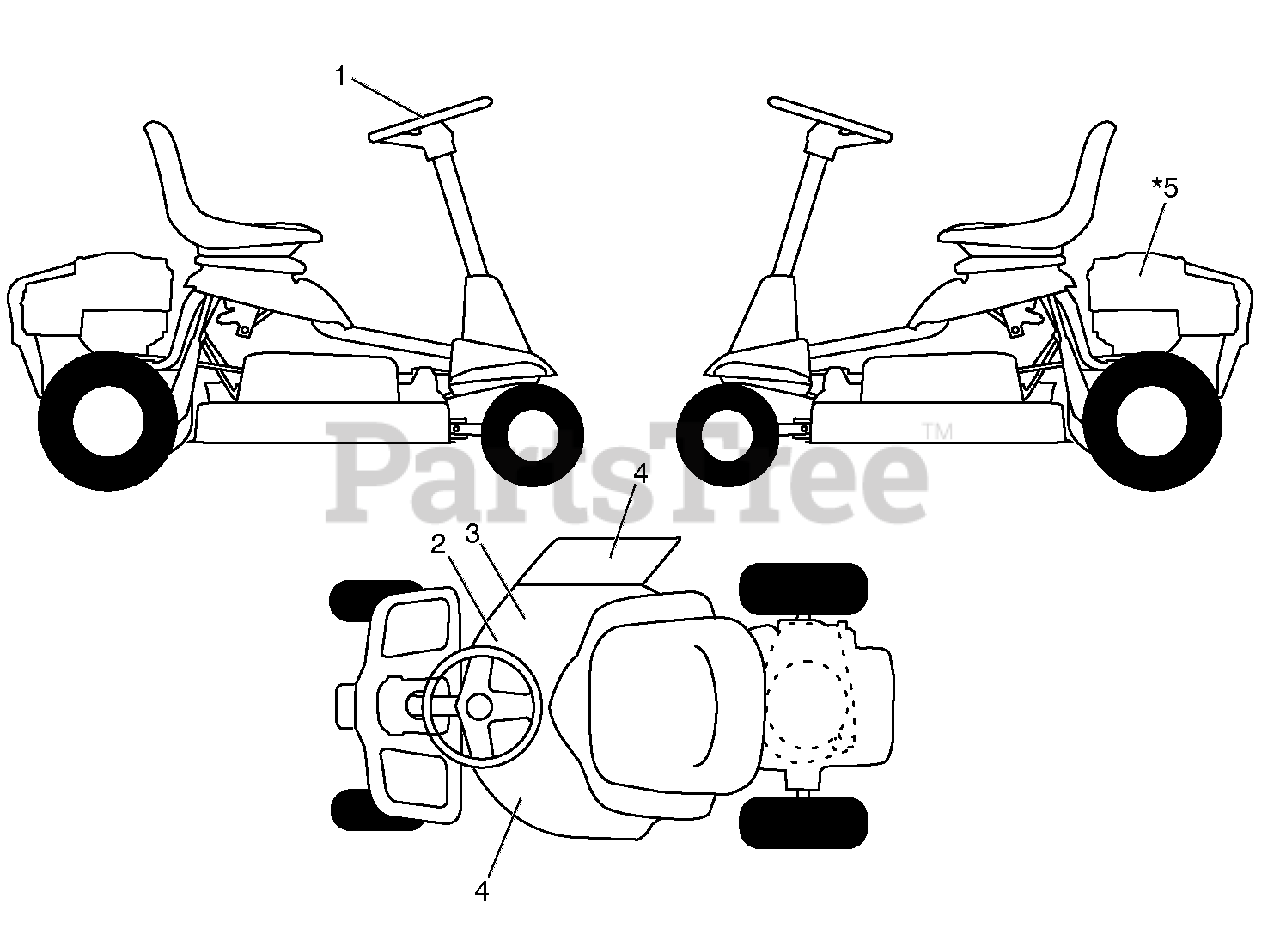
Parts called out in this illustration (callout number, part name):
1	DECAL, STEERING WHEEL
2	DECAL, V-BELT SCH 30"
3	DECAL, WARN. DEFLECT/CTFGR
4	DECAL, DECK/DEFLECTOR
5	DECAL, SPARK ARRESTOR
5	DECAL, BYPASS
